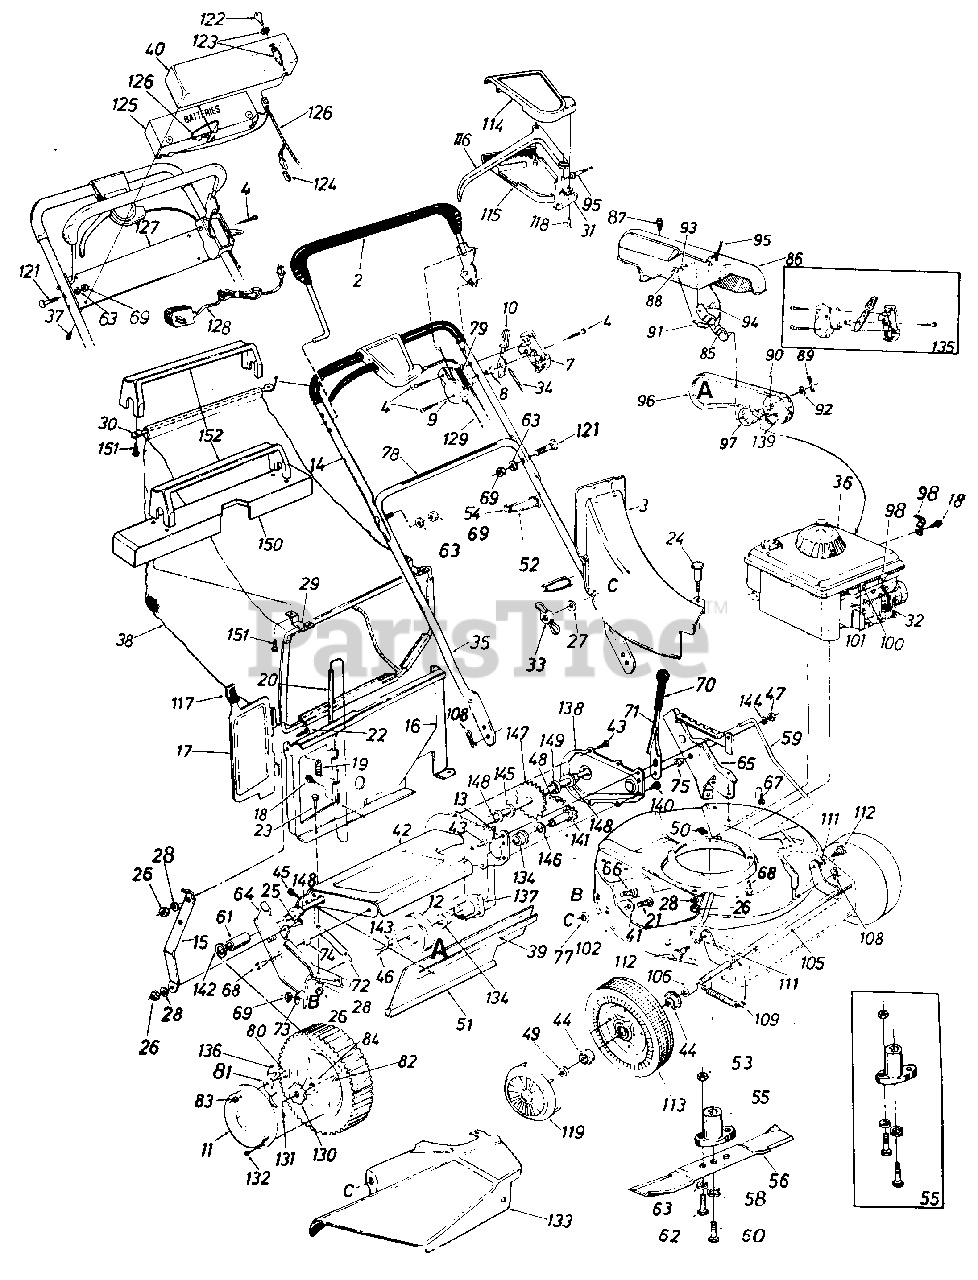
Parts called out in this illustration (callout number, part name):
2	Control Handle Ass'y. L.H.
3	Top Discharge Chute Ass'y.
4	Truss Mach. Scr. #12 x 1.50" Lg.
7	Control Panel Half
8	Control Disc Pin
9	Clutch Panel Half
10	Throttle Control Lever
11	Hub Cap
12	1/2" V-Pulley
13	Cotter Pin 3/32" Dia. x .75"
14	Upper Handle Chrome
15	Panel Support Brkt.
16	Top Catcher Panel
17	Top Door
18	Hex B-Tap Scr. #10 x .38"
19	Torsion Spring
20	Pivot Pin
21	Carriage Bolt 1/4-20 x .62
22	Truss Mach. Scr. 1/4-20 x .62" Lg.
23	Hex Bolt 1/4-20 x .50" Lg.
24	Shoulder Bolt .312 Dia. x .18 Lg. Special
25	Hex Bolt 1/4-20 x .62" Lg.
26	Hex Nut 1/4-20 Thd.
27	Fl-Wash. .280" I.D. x .620"
28	L-Wash. 1/4" I.D.
29	Front Grass Catcher Frame
30	Grass Catcher Handle
31	S.P. Control Cover
32	Spark Plug Insulator
33	Wing Nut
34	Throttle Control Wire 58"
35	Lower Handle Chrome
36	Engine
37	Truss Mach. Hi-Riser Tap Scr. 1" Lg.
38	21" Top Discharge Grass Bag
39	Retaining Strip
40	Battery Tray
41	Fl-Wash. .344" I.D. x .62"
42	Chain Axle Ass'y.
43	Hex B-Tap Scr. 1/4" x .38" Lg.
44	Flange Ball Bearing 1/2" I.D.
45	Hex AB-Tap Scr. 1/4 x .62"
46	Hex Wash. TT-Tap Scr. 1/4-20
47	Hex Patch L-Nut 3/8-24 Thd.
48	#48 Chain .500" Pitch x .30 Links
49	Hex L-Nut 1/2-20 Thd.
51	Rear Flap 3.75" x 17.30" Lg.
52	Cable Tie
53	Hex Nut 5/16-24 Thd.
54	Cable Anchor
55	Blade Adapter Kit
56	21" Blade
58	L-Wash. 3/8" I.D. H.D.
59	Height Adj. Rod 19.42" Lg.
60	Hex Bolt 3/8-24 x 2.25" Lg. (Grade 5)
61	Spacer .51" I.D. x .69" O.D. x.69" Lg.
62	Hex Bolt 5/16-24 x 1.00" Lg. (Grade 5)
63	L-Wash. 5/16" I.D.
64	R.H. Handle Wheel Brkt. Ass'y.
65	L.H. Handle Wheel Brkt. Ass'y.
66	Carriage Bolt 5/16-18 x .62"
67	Hex Wash. Hd. B-Tap Scr. 5/1 6-18
68	Hex Wash. Hd. TT-Tap Scr. 3/8-1 6
69	Hex Nut 5/16-18 Thd.
71	Height Adj. Lever
72	Extension Spring .50" O.D. x 3.80" Lg.
73	Bell-Wash. 5/16" I.D.
74	Spacer .385" I.D. x .502" O.D. x .270" Lg.
75	Shld. Spacer .500" Dia. x .100
77	Bolt Retainer 1/4 x .50" O.D.
78	Instruction Label
79	Control Label
80	Shld. Scr. .342" Dia. x .268
81	Pawl
82	Wheel Ass'y. Comp. Rear 8 x 1.75
83	Hex Ins. L-Nut 1/4-20 Thd.
84	Flange Ball Bearing 1/2" I.D.
85	Belt Idler Bracket Ass'y.
86	Belt Cover
87	Hex Wash. S-Tap Scr. 1/4-20 x.50" Lg.
88	Hex Nut 1/4-20 Thd.
89	Cotter Pin 118" Dia. x 1.00" Lg.
90	Spring Pin Spir. 3116" Dia. x 1.00" Lg.
91	Extension Spring .33" O.D. x 1.12" Lg.
92	Fl-Wash. .531" I.D. x .930" O.D. x .050
93	L-Wash. 1/4" I.D.
94	Shld. Bolt .375" Dia. x .181
95	S.P. Cable x 53.0" Lg.
96	"V"-Belt 1/2" X 32.0" Lg.
97	Fl-Idler Plastic 1.62" Dia.
98	Casing Clamp
100	Hex B-Tap Scr. #10 x .62"
101	Casing Clamp
106	Sleeve .526" I.D. x .690" O.D. x .880" Lg.
108	Intern. Cotter Pin 5/16" Dia.
109	Extension Spring .50" O.D. x 3.20" Lg.
111	Intern. L-Wash. 3/8 I.D.
112	Shld. Bolt .623" Dia. x .425
113	Front-Wheel Ass'y. Comp. 7x 1.50
114	Self-Propelled Control Cover
115	Self-Propelled Control Cover
116	Control Lever
117	Door Grip
118	Fl-"C"-Sunk Hd. Tap Scr. #10 x .75" Lg.
119	Hub Cap Plastic
121	Curved Carr. Bolt 5/16-18 x 1.38" Lg.
122	Ignition Key
123	Ignition Switch
124	Plug
125	Battery Pack
126	Wire Harness
127	Lower Battery Tray
128	Battery Charger
129	Control Cable 43" Lg.
130	Ratchet Wheel 1.62" O.D.
131	Cotter Pin 1/8" Dia. x 1.00" Lg.
132	Pan Hd. Tap Scr. #12 x .50" Lg.
133	Side Chute Deflector Ass'y.
134	Flange Bushing
135	Kit Control Housing Comp.
136	Spring Nylon
137	Bearing Hub Flange Ass'y.
138	Chain Cover
139	Engine Pulley 1/2"
140	Hex Wash. S-Tap Scr. 1/4-20 x.50" Lg.
141	Sprocket Shaft Ass'y.
142	Fl-Wash. .531" I.D. x .93" O.D.
143	Bell-Wash. .265" I.D. x .75" 0. D.
144	Fl-Wash. .385" I.D. x .87" O.D.
145	Fl-Wash. .51" I.D. x 1.0" O.D.
146	Fl-Wash. .62" I.D. x 1.12" O.D.
147	Rear Shaft Ass'y. 22.05" Lg.
148	Hex Flange Bearing .506" I.D. Plastic
149	Spacer .510" I.D. x 1.00" O.D. x .210" Lg.
150	Catcher Frame Cover
151	Truss Mach. Tap Scr. 1" Lg.
152	Bag Handle
